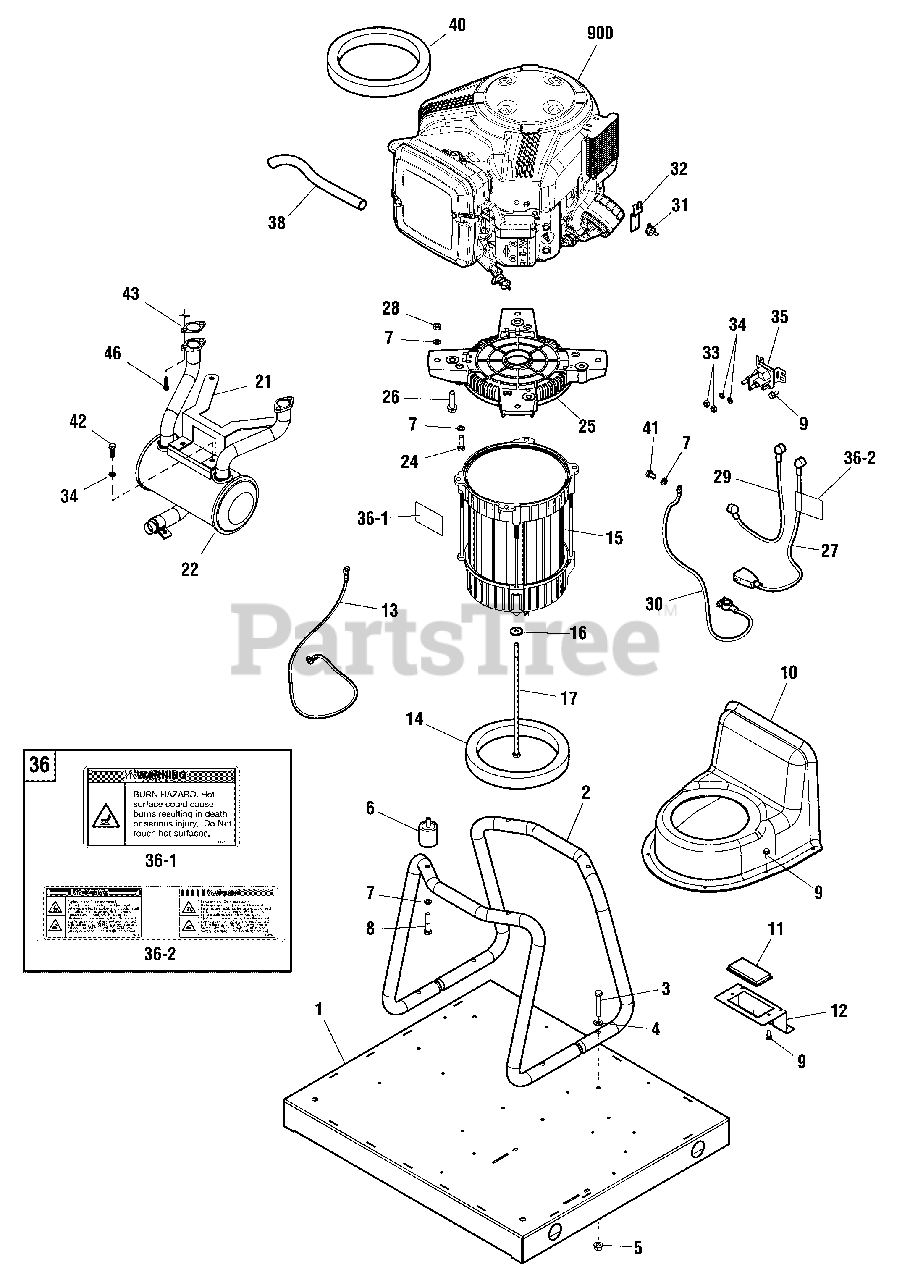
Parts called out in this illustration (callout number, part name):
6	MOUNT-VIBRATION
9	BOLT
11	REGULATOR-VOLTAGE
15	ALTERNATOR
21	BRACKET-MUFFLER
26	SCREW
27	WIRE
29	WIRE, Starter Solenoid
30	WIRE, Battery, Negative
32	PLATE-TEMP SWITCH
35	SOLENOID, Starter
36	DECAL SHEET-WARNINGS
36-1	DECAL, Warning, Burn Hazard
36-2	DECAL, Warning, Explosion
43	GASKET, Exhaust
900	** ENGINE
